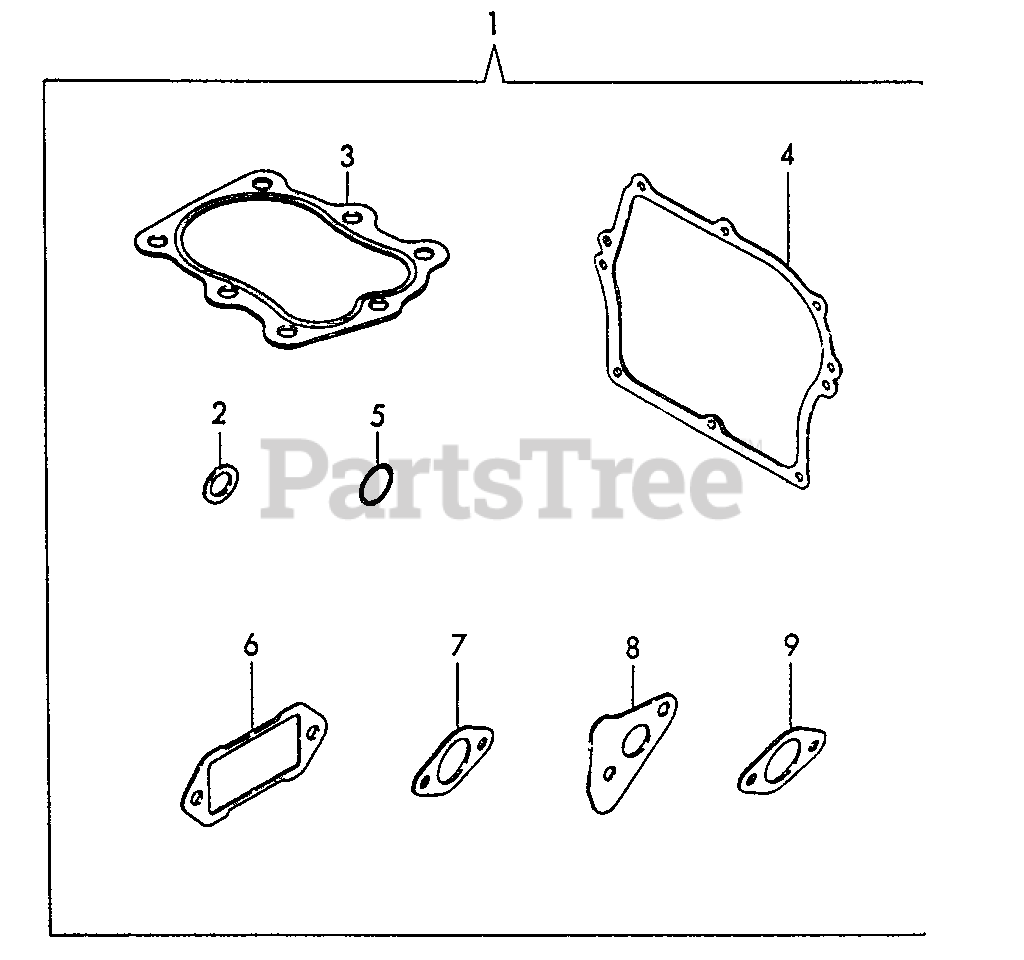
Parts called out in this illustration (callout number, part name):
1	GASKET KIT
2	GASKET
3	GASKET, CYLINDER
4	GASKET, SIDE COVER
5	O-RING - 18
6	GASKET, BREATHER
7	GASKET, INTAKE
8	GASKET, EXHAUST
9	GASKET, EXHAUST
